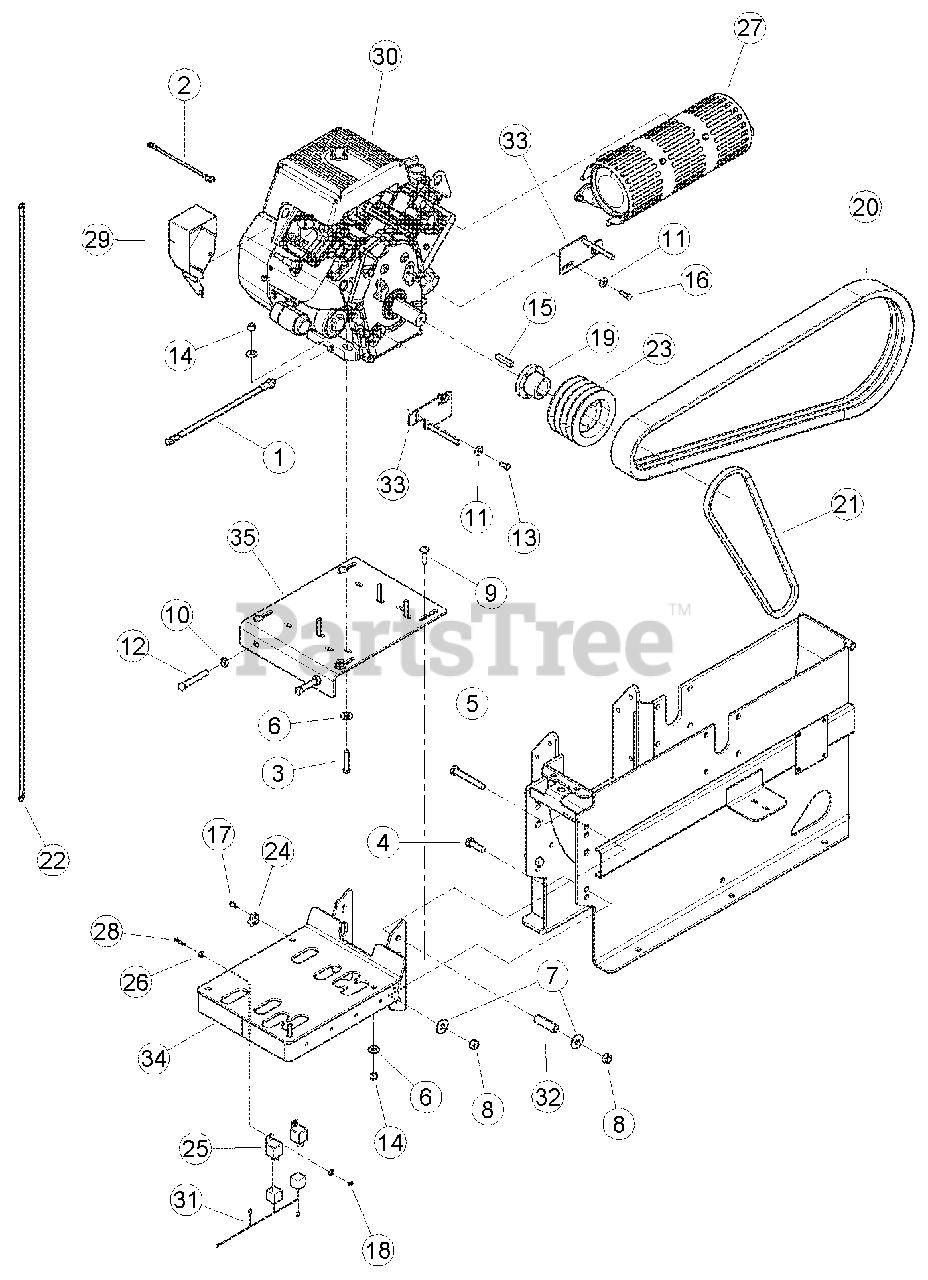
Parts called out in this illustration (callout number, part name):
1	HOSE ASSY, CRANKCASE DRAIN
2	CABLE, 50" NEG (R / R)
3	BOLT, 3/8 X 2 HEX HD GR5 ZP
4	BOLT, 1/2 X 1-1/2 HEX HD GR5 ZP
5	BOLT, 1/2 X 3-1/2 HEX HD GR5 ZP
6	WASHER, 3/8 FLAT ZP
7	WASHER, 1/2 FLAT ZP
8	NUT, 1/2 CENTERLOCK GRB ZP
9	BOLT, 3/8 X 1-1/2 CRG GR5 NC ZP
10	NUT, 1/2 JAM NC ZP
11	WASHER, 5/16 FLAT ZP
12	SET SCREW, 1/2 X 3 SQ HD 1/2 DOG PT
13	BOLT, 5/16-24 X 3/4 HEX HD GR5 ZP
14	NUT, 3/8 NYLOCK ZP
15	KEY, 3/8 SQUARE X 2 LONG PLAIN
16	BOLT, 5/16-24 X 1 HEX HD GR5 ZP
17	RIVET, AL BLIND 1/4 X 3/4 DOME HEAD
18	NUT, #10-24 K-LOCK ZP
19	BUSHING, SD 1-7/16"
20	BELT, 3B83 BANDED
21	BELT, BX44
22	CABLE, BATTERY POSITIVE 66"
23	SHEAVE, 4B5.2 SD
24	CLAMP, CABLE MOUNT
25	RELAY, 12V SPDT W/ FLANGE
26	WASHER, #10 FLAT ZP
27	MUFFLER, SUBARU V-TWIN (FOR SERVICE SEE ENGINE OWNER'S MANUAL OR YOUR NEAREST AUTHORIZED SUBARU INDUSTRIAL ENGINE DEALER.)
28	SCREW, #10 X 1 PAN HEAD SLOTTED
29	CONTROL, SUBARU V-TWIN IGNITION (FOR SERVICE SEE ENGINE OWNER'S MANUAL OR YOUR NEAREST AUTHORIZED SUBARU INDUSTRIAL ENGINE DEALER.)
30	ENGINE, SUBARU 720CC EH72 EFI (FOR SERVICE SEE ENGINE OWNER'S MANUAL OR YOUR NEAREST AUTHORIZED ISUBARU INDUSTRIAL ENGINE DEALER.)
31	HARNESS, SAFETY RELAY
32	SPACER, .75 X 2.06
33	WELDMENT, BELT KICKER
34	WELDMENT, ENGINE BASE
35	WELDMENT, ENGINE MOUNT PLATE
